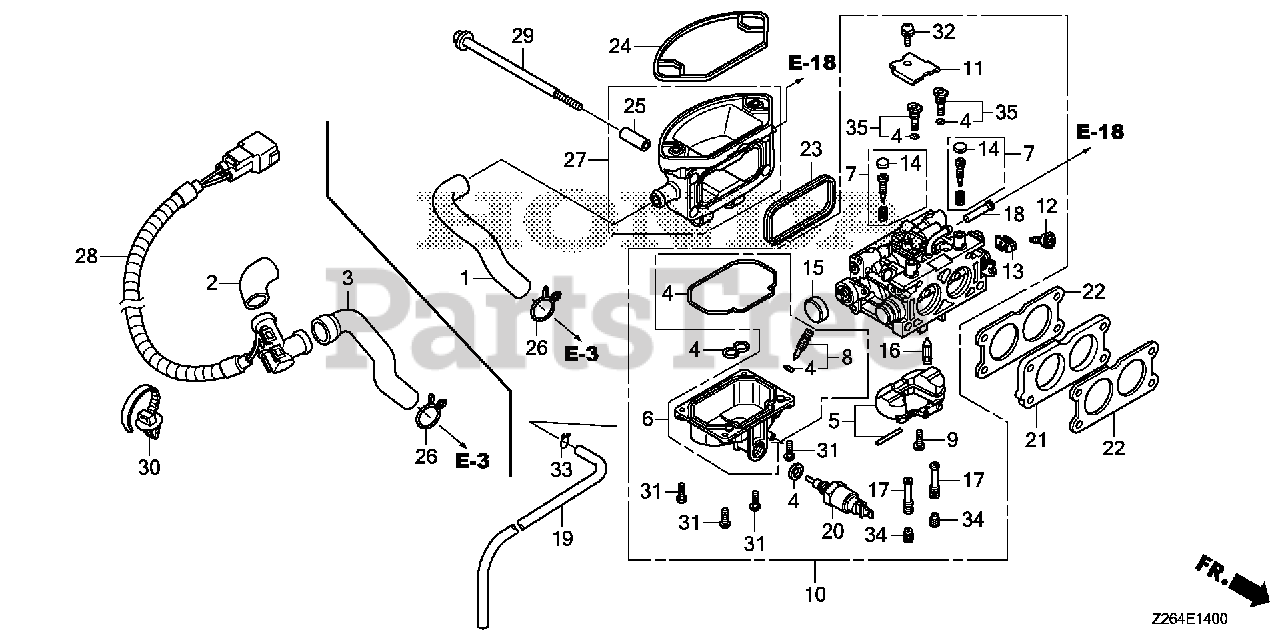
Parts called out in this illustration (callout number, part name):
1	TUBE, BREATHER
4	GASKET SET
6	CHAMBER SET, FLOAT
8	SCREW SET, DRAIN (ADVENTURE GREEN) (CARBURETOR NO.)
9	SCREW, FLOAT
10	CARBURETOR ASSY. (BK07W A)
12	SCREW, THROTTLE STOP
13	ARM, THROTTLE LINKAGE
14	CAP, ADJUSTING SCREW (CARBURETOR NO.)
15	CAP, CHOKE LEVER DUST
16	VALVE, FLOAT
17	NOZZLE, MAIN
18	SCREEN, FUEL STRAINER
19	TUBE, DRAIN
20	VALVE ASSY., SOLENOID
21	INSULATOR, CARBURETOR
22	GASKET, CARBURETOR
23	GASKET, AIR CLEANER
24	SEAL, AIR CLEANER HOUSING
25	COLLAR, AIR CLEANER Use from Engine SN 1786085.
26	CLIP, BREATHER TUBE
27	ELBOW, AIR CLEANER
29	BOLT, FLANGE (6X106)
31	SCREW, PAN (4X12)
32	SCREW-WASHER (5X10)
33	CLIP, TUBE (B8)
34	JET, MAIN (#100) Use from Engine SN BE87A A to BE87A A.
34	JET, MAIN (#105) Use from Engine SN BE87H A.
34	JET, MAIN (#110) (CARBURETOR NO.)
35	JET SET, PILOT (#40) (ADVENTURE GREEN) (CARBURETOR NO.)
